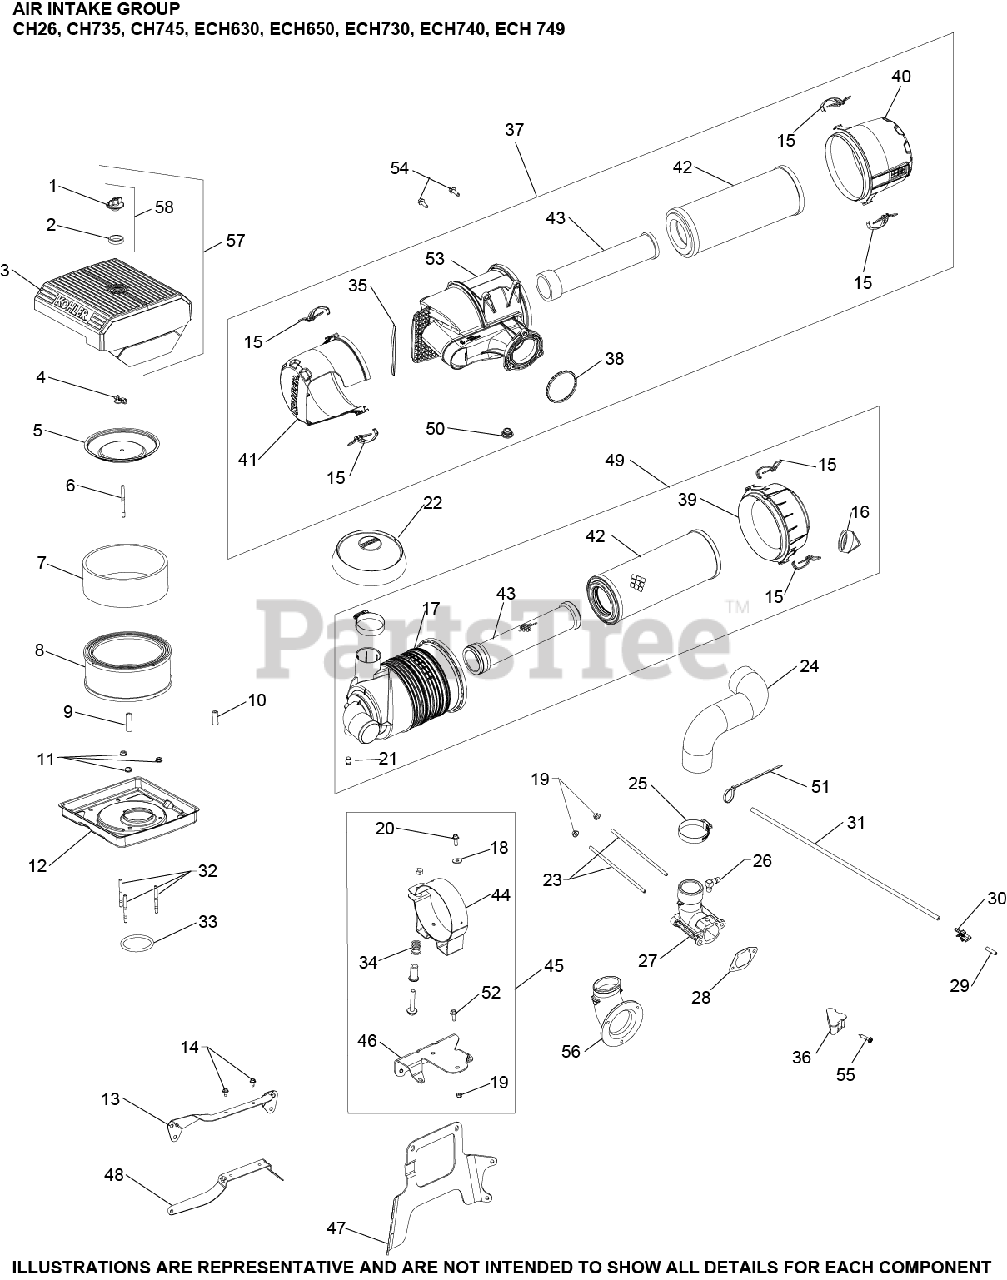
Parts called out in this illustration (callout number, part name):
1	KNOB, COVER
3	COVER, AIR CLEANER
4	NUT, WING
5	COVER, INNER AIR CLEANER
6	STUD, LOW PROFILE A/C
7	PRE-CLEANER (HIGH)
8	ELEMENT, AIR FILTER (HIGH) - Also available Retail Packaged 24 883 03-S1 Air Filter Kit
12	BASE, AIR CLEANER
13	BRACKET, AIR CLEANER BASE
14	SCREW, THREAD FORMING
33	O-RING, AIR CLEANER BASE
36	COVER, BLOWER HOUSING USE 24 096 160-S
55	SCREW, HEX WASHER HI-LO
57	KIT, AIR CLEANER COVER
58	KIT, KNOB W/SEAL
